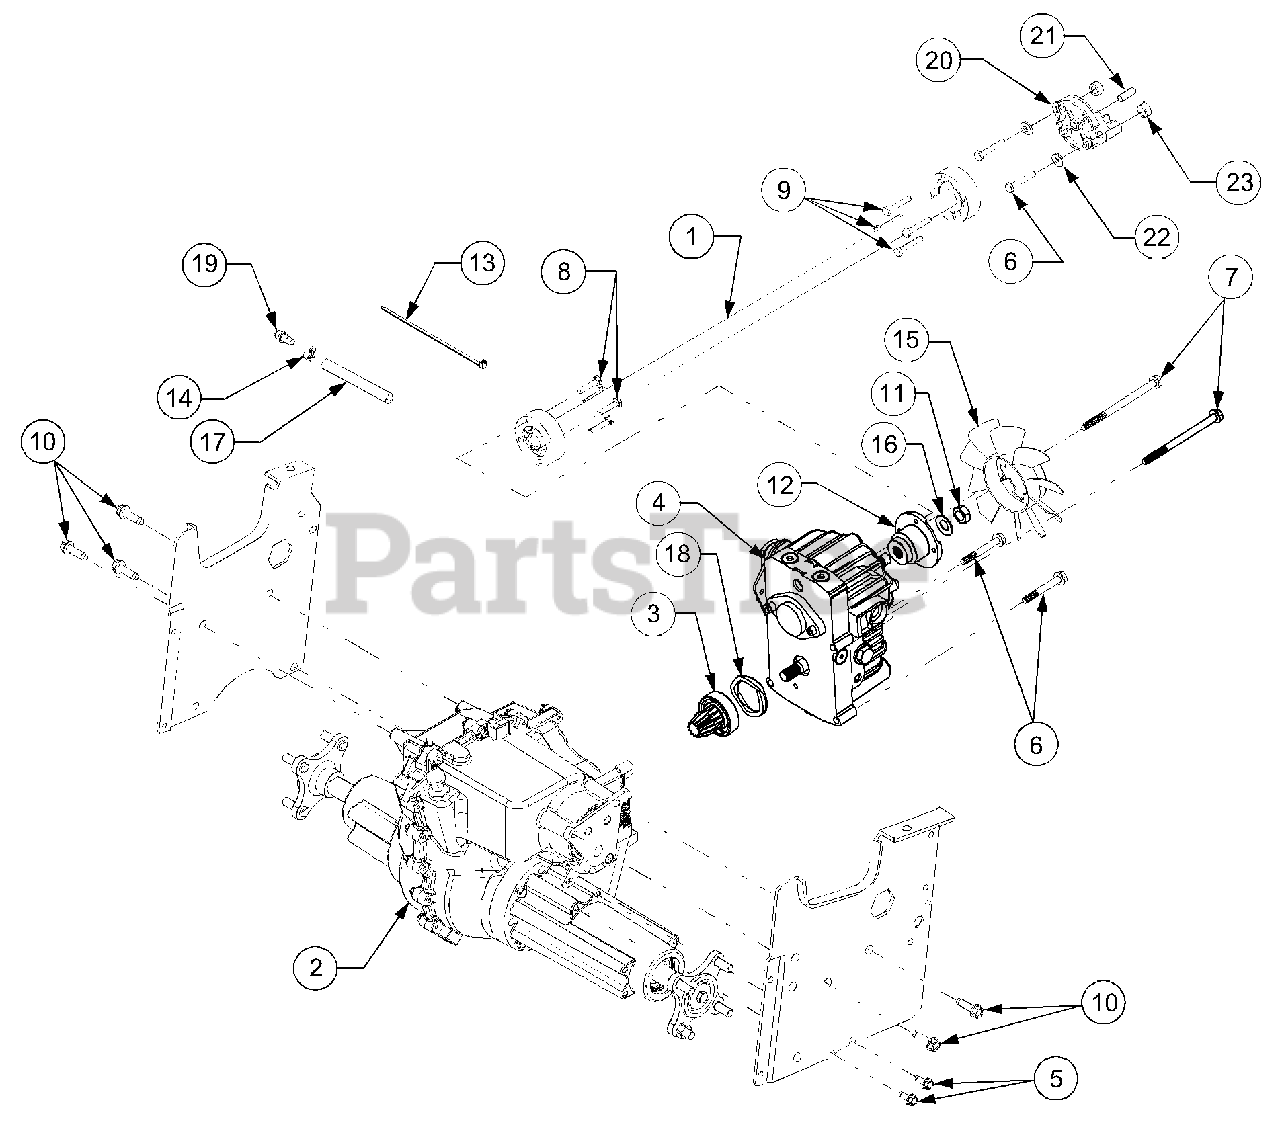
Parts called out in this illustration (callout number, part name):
1	Shaft Assembly, Drive, 29.06 Lg
2	Transmission Assembly (Double D)
3	Pinion Assembly, Input
4	Pump, Hydrostatic
5	Screw, Hex Wsh Tap, 5/16-18 x .75
6	Screw, Hex Cap, 5/16-18 x 1.75 GR5
7	Screw, Hex Cap, 5/16-18 x 4.5 GR5
8	Screw, Hex Patch, 1/4-20 x 1.25 GR5
9	Screw, Hex Patch, 1/4-20 x 1.62 GR5
10	Screw, Hex Wsh Tap, 3/8-16 x 1.25
11	Nut, Hex Top Lock Jam GR5, 1/2-20
12	Adapter, Pump
13	Tie, Self-Clinch Cable
14	Clamp, Hose
15	Fan, 10 Blade Cooling
16	Washer, Bell, 1/2 ID
17	Line, Fuel, 7in (10ft Bulk)
18	Washer, Wave, 1.96 x 2.44 x .06
20	Adapter, Drive Shaft
21	Pin, Locating, .352 Dia x 1.156
22	Washer, Flat, .344 x .75 x .12
23	Spacer, .38 x .625 x .275
